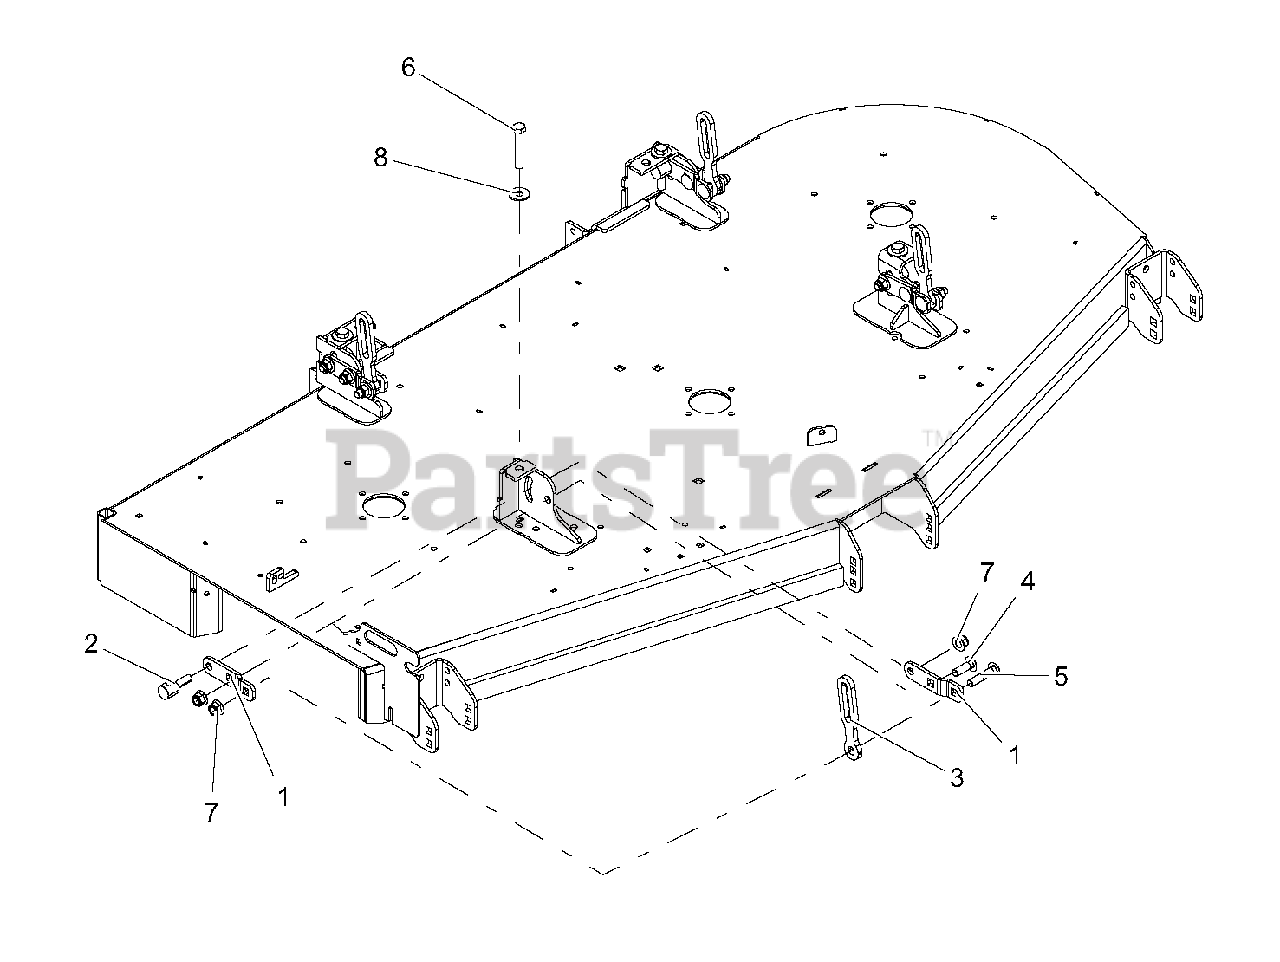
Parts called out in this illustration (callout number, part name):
1	BRKT, DECK LEVELING-BLACK
2	TRUNNION, .50-13
3	LINK, DECK LIFT
4	@BLT-RDHDSQNK .50-13X1.50 G5 YWZC
5	BLT-RDHDSQNK .50-13X2.25 G5
6	BLT-HEX .50-13X3.00 GR5 FTH YWZC
7	NUT-LK-NYL-FLG .50-13 YWZC
8	@WSHR-FL-STL.563X1.38X.109YWZC
